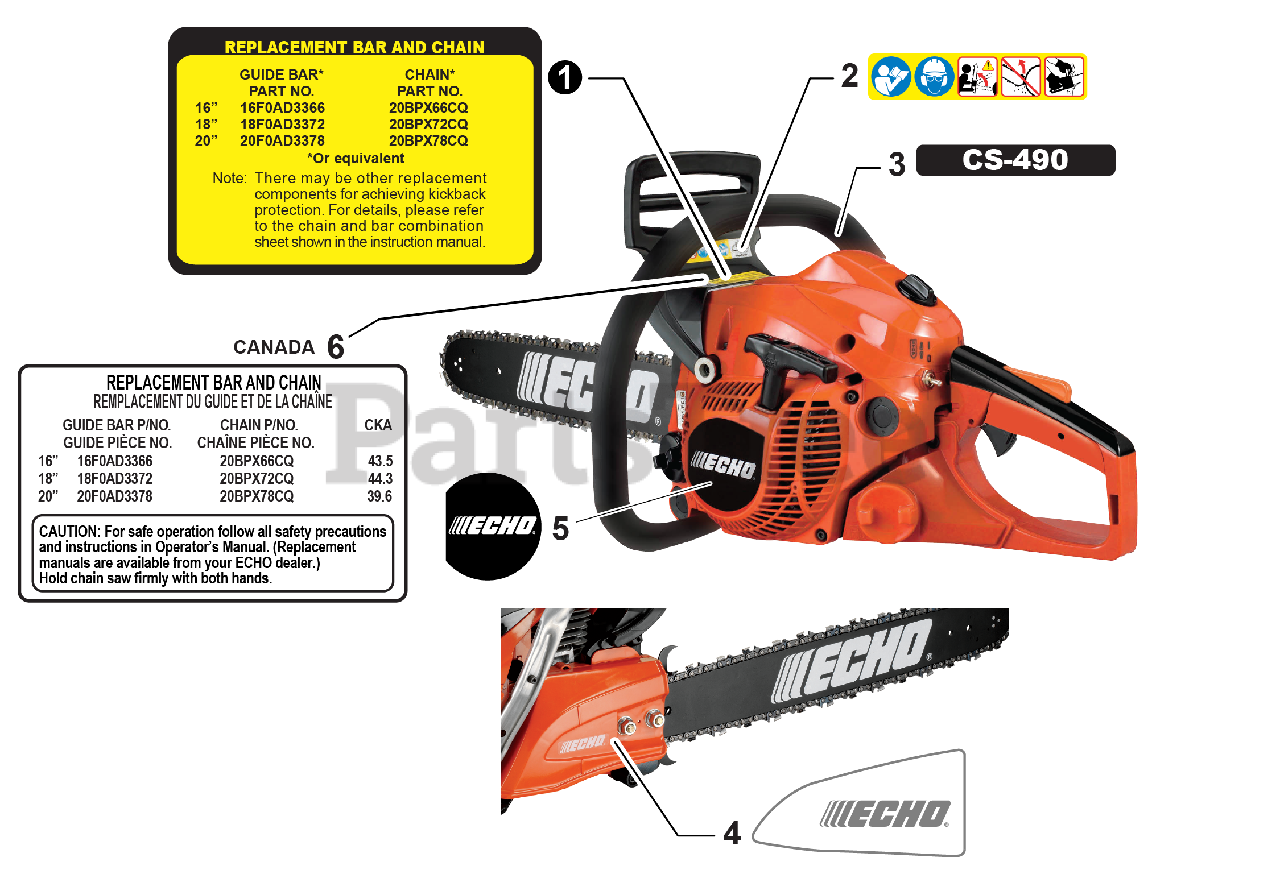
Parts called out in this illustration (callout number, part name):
1	LABEL, BAR & CHAIN
2	LABEL, CAUTION
3	LABEL, CS-490
4	LABEL, ECHO
5	LABEL, ECHO
6	LABEL, BAR & CHAIN
